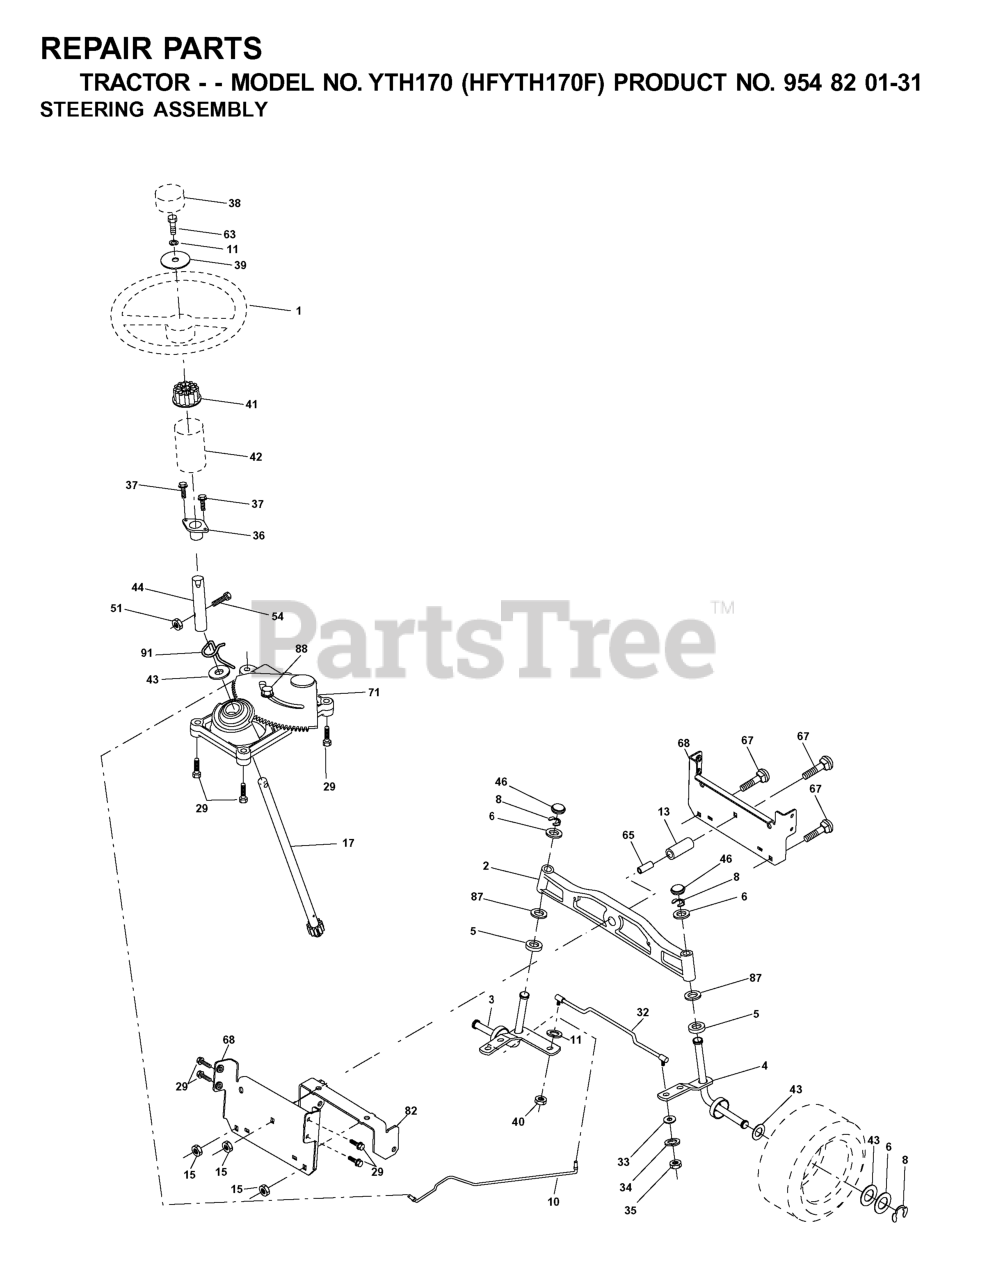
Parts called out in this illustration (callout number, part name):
1	WHEEL.STEERING.LEGEND.BLK
1	STEERING WHEEL
2	AXLE ASM
3	SPINDLE.ASM.LH.15"TIRES
4	SPINDLE.ASM.RH.15"TIRES
5	THRUST WASHER
10	DRAGLINK.15".TIRES.2001
11	WASHER, LOCK 3/8
13	TUBE, PIVOT AXLE
15	NUT
17	SHAFT ASM
29	SCREW 3/8-16X3/4
33	WASHER M
34	WASHER.LOCK.HVY.HLCL.SPR.5/16
35	NUT, CROWNLOCK
36	BUSHING, STEERING
37	SCREW.TT.#10-32X.5.3/8.FLANGE
38	CAP.WHEEL.STEERING.GREY
39	Washer 13/32 x 1-1/20 x 11 Gauge
40	GRIPCO NUT
41	STEERING WHEEL ADAPTOR
42	STEERING BOOT, GRAY
44	EXT SHAFT STEERING
46	CAP.SPINDLE.BLACK
51	NUT.71038.31-18.HEX.NYLOCK
54	BOLT.5/16-18X1-1/4 FULL.THREAD
65	SPACER BRACE AXLE
67	BOLT
68	BRACE.AXLE.15"TIRES
71	STEERING ASM
82	BRACKET
87	WASHER, FLAT .781 X 1 1/2"
88	BOLT, SHOULDER 7/16-20
91	CLIP.STEERING
